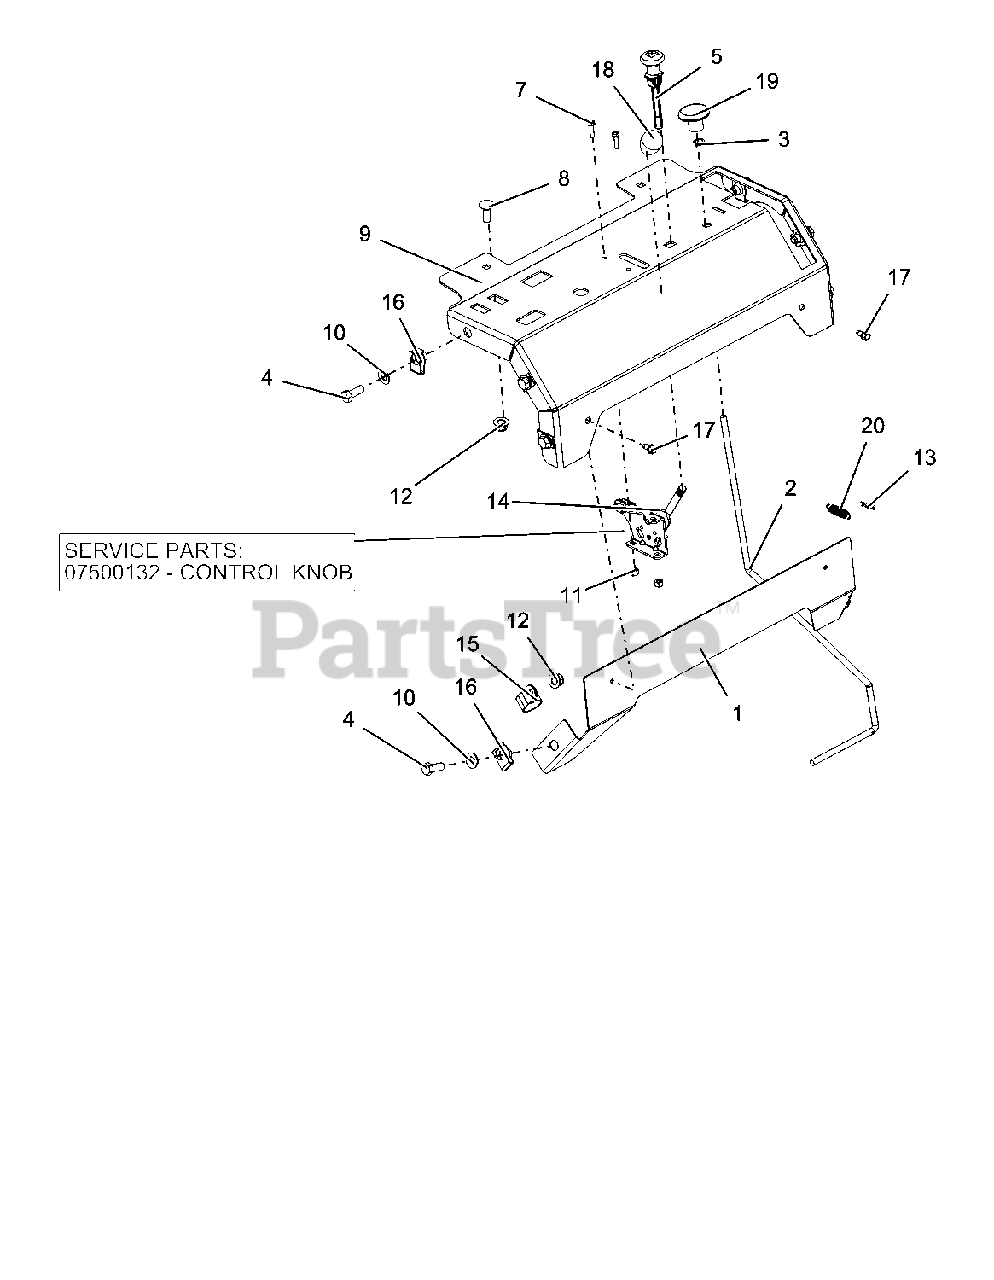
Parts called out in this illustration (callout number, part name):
1	PLATE, FRONT BACKER
2	WIREFORM, TRAILER LOCK
3	BUSHING, POLYLINER-.38 SNAPIN
4	@BLT-HEX .38-16X1.00 GR5 YWZC
5	CABLE, CHOKE (SNAP IN)
7	@SCR-MCH 10-24X.75 HWH YWZC
8	@BLT-RDHDSQNK .38-16X1.00 G5YZ
9	KIT, SERVICE COMP. STANCE DASH
10	@WSHR-FL-STL.406X.812X.065 YWZ
11	@NUT-LK-NYL 10-24 W/INSRT YWZC
12	@NUT-LK-NYL-FLG .38-16 YWZC
13	PIN-HAIR, ENDRIES #25 YWZC
14	KNOB-CONTROL-BLACK .38-16X.50
14	CABLE, PRO-CONTROL
15	CLAMP, COUSHIONED STEEL REV
16	NUT-RTNR .375-16X.37
17	SCR-TAP .25-20X.50 HWH TR YWZ
18	KNOB-CONTROL-BLACK .38-16X.50
19	KNOB, PUSH-PULL .312-18
20	SG-TENS .048X.44X1.75 WLD 9
